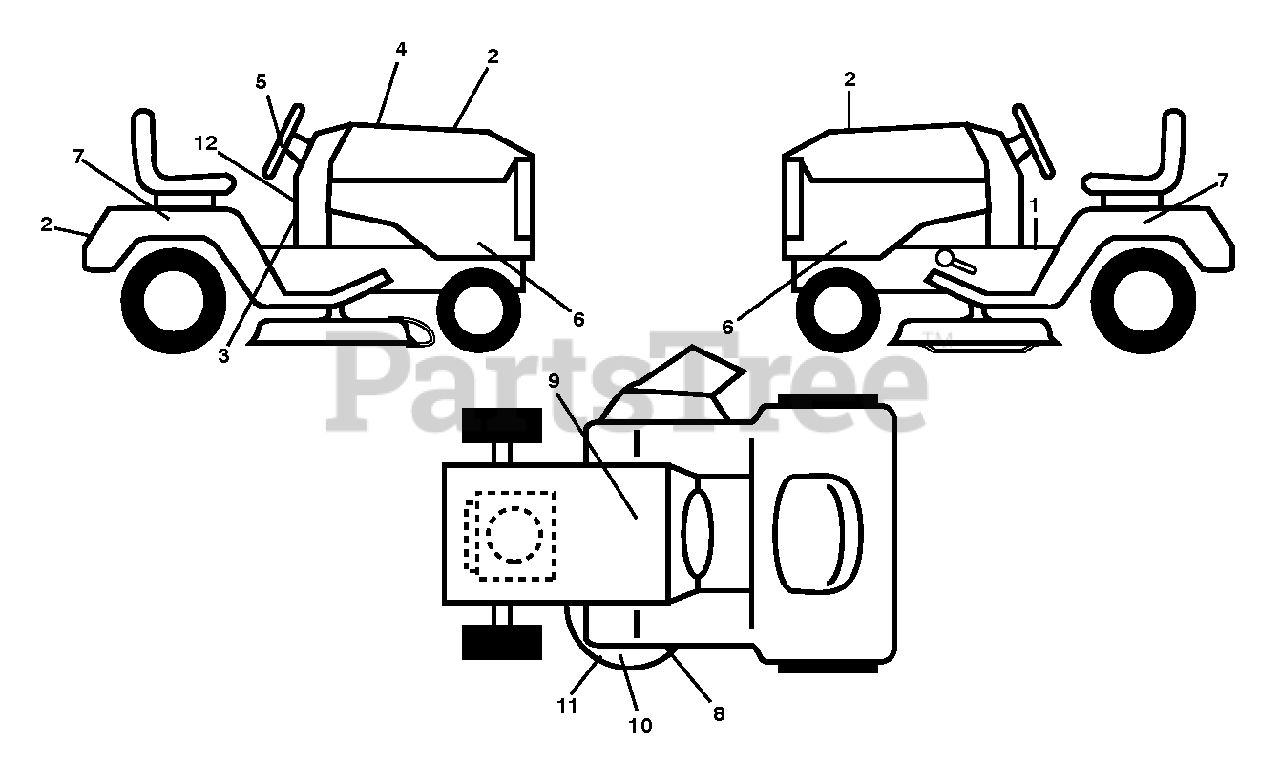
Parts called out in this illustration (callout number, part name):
3	DECAL, WARNING SPARK ARRESTOR
8	DECAL.MOWER.SCH.48/54
9	DECAL BTRY SYMBOLS
10	DECAL
11	DECAL.MOWER
